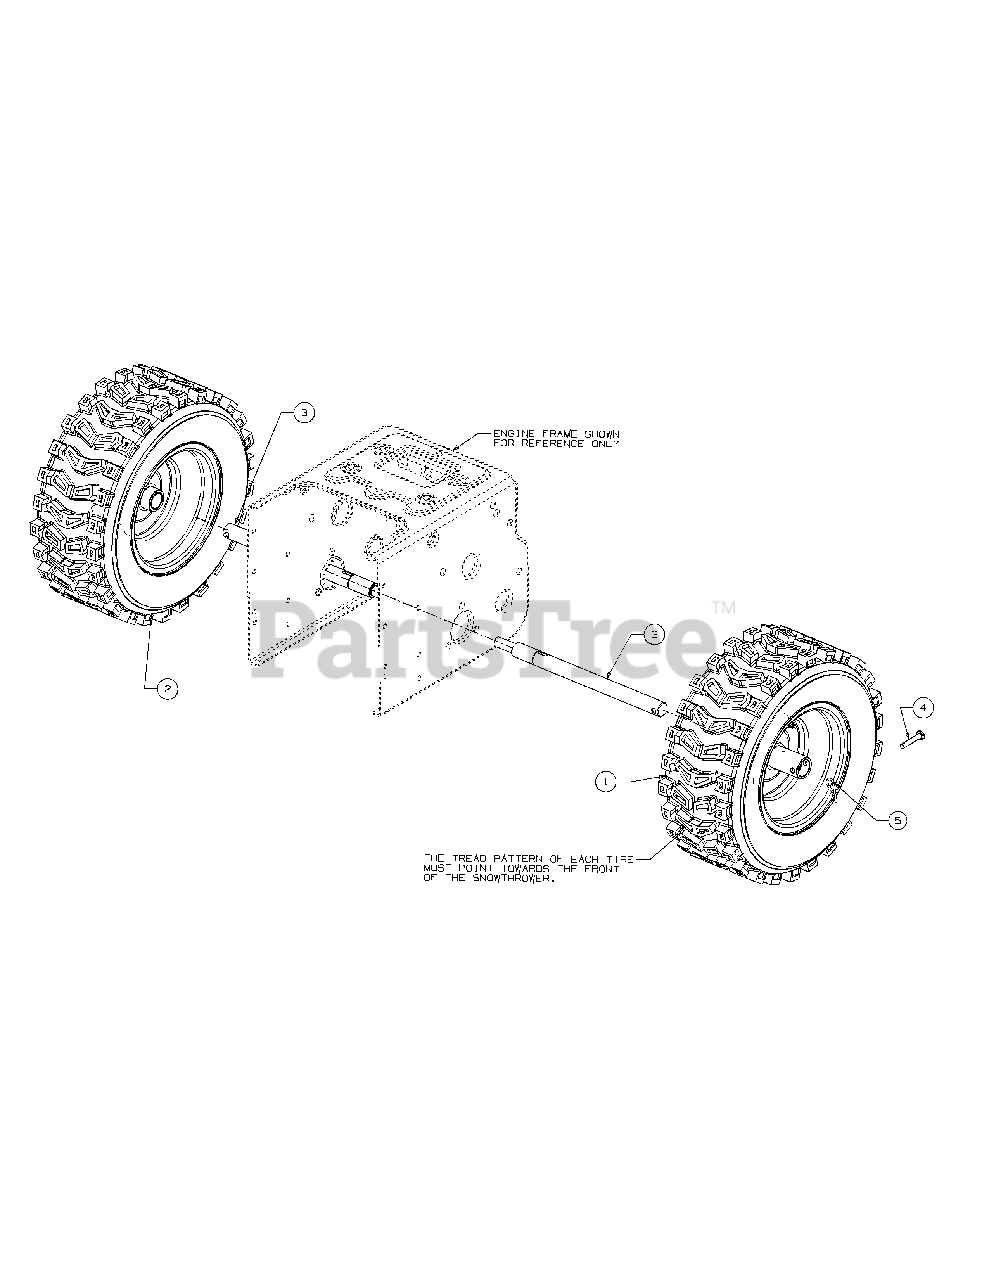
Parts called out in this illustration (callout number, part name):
1	Wheel-Compl 16 X 6
2	Wheel Comp-16 X 6.
3	Axle:Wheel: .995
4	Pin:Clevis
5	Pin-Cotter
